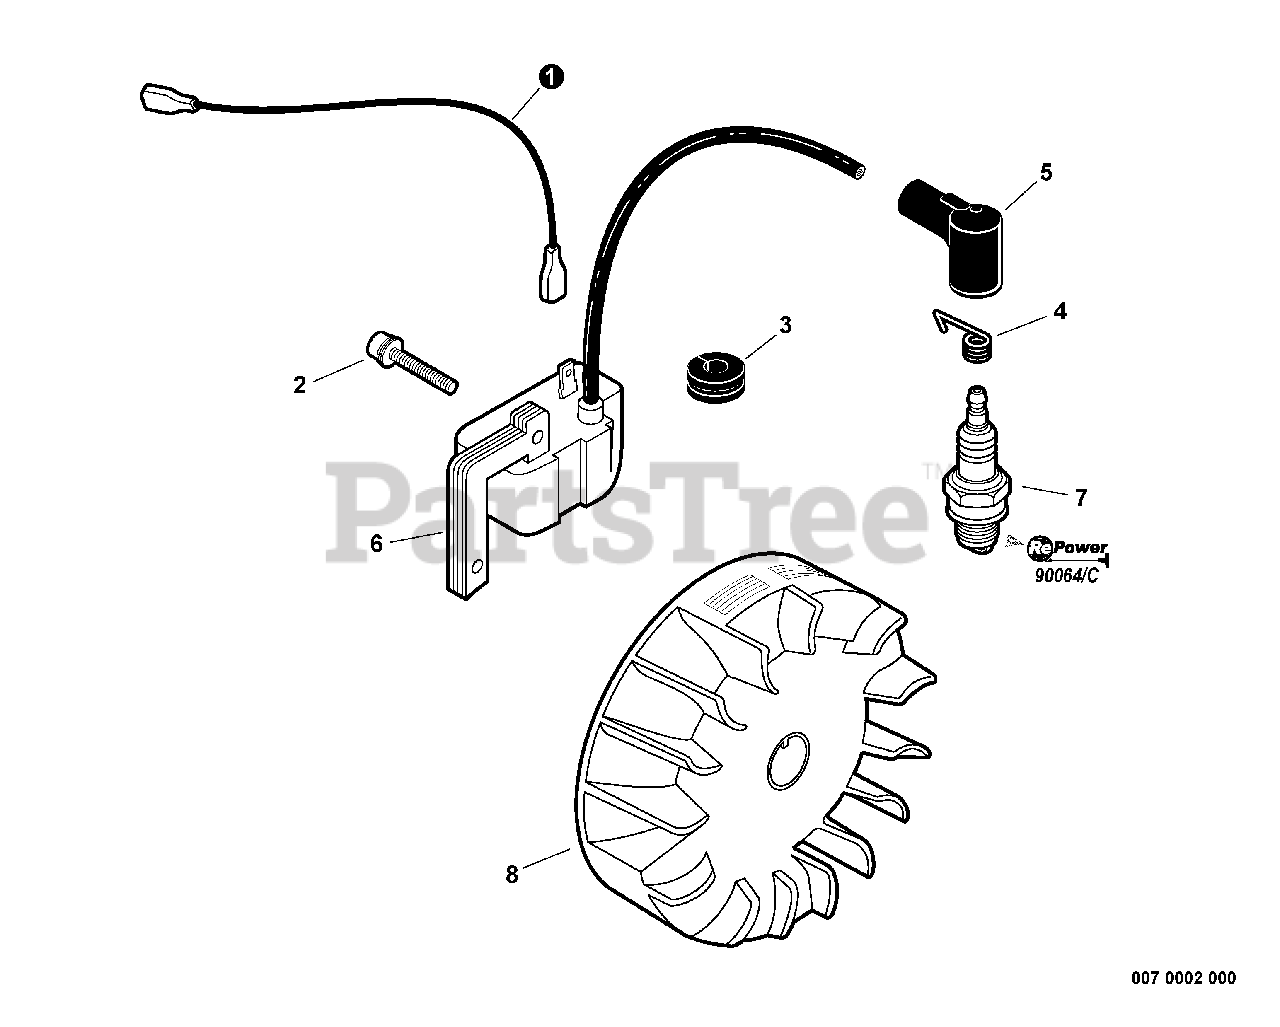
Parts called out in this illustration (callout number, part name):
1	LEAD - IGNITION
2	SCREW - 4X22
3	GROMMET
4	TERMINAL, SPARK PLUG CAP
5	CAP, SPARK PLUG
6	COIL, IGNITION
7	SPARK PLUG -- BPM-7A
7	SPARK PLUG -- BPMR-7A
8	FLYWHEEL
9	RePower TUNE-UP KIT
